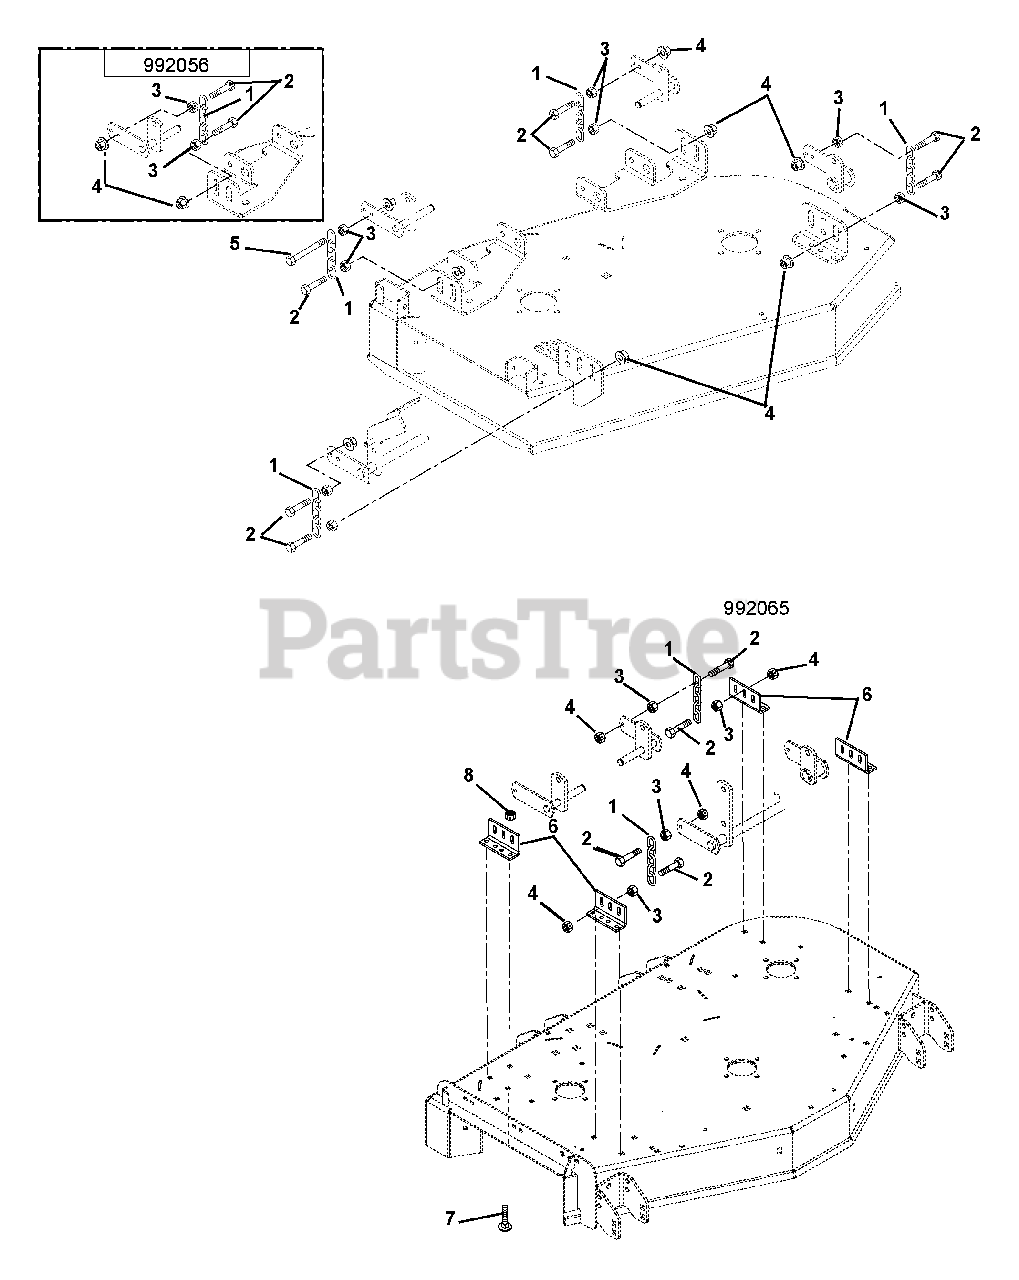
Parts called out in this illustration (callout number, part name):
1	Chain, Link
2	Bolt, Hex M12-1.75 x 55 Grade 5 (314)
2	Bolt, Hex M12-1.75 x 55 Grade 5 (056, 065)
3	Nut-Spin Lock-Flange M12-1.75
4	Nut-Locking-Top-Flange M12-1.75
5	Bolt-Hex .50-13 x 3.00 Grade 5 (314)
6	Bracket, Mower Mounting (065)
7	Bolt, Round Head Square Neck .38-16 x 1.00 Grade 2 (065)
8	Nut, Nyloc Flange 3/8-16 (065)
